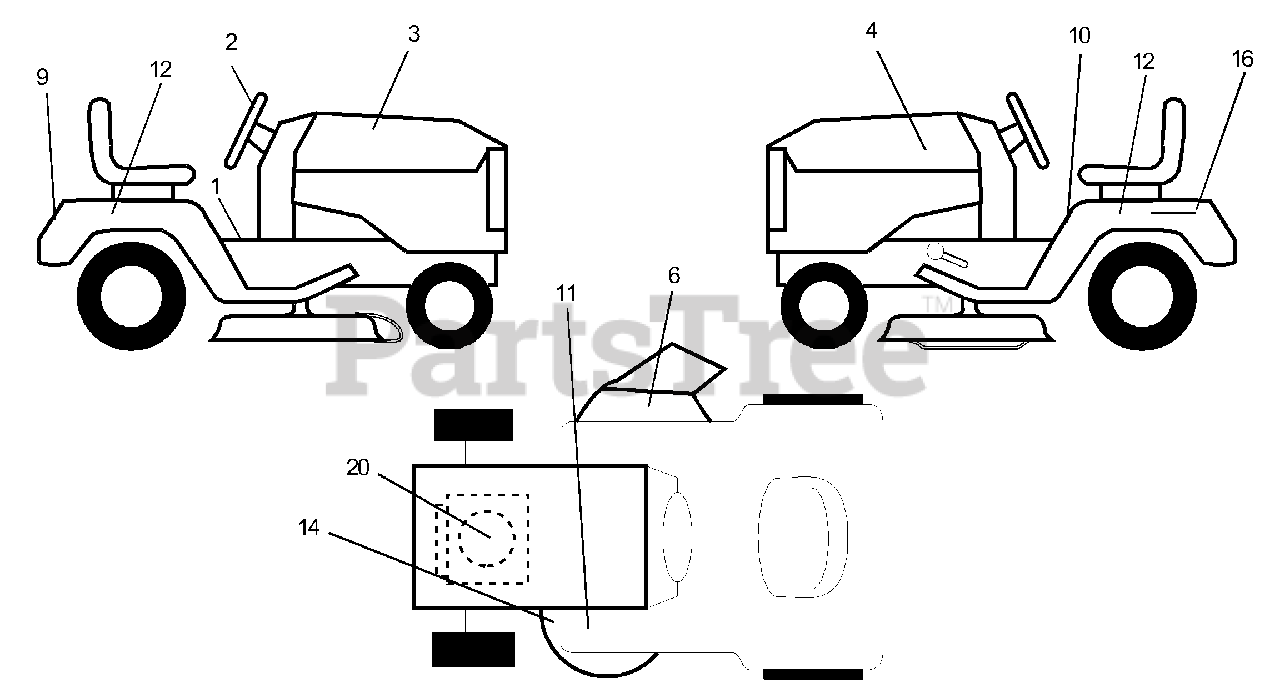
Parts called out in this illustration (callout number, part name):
1	Decal Instruction Operat English/French
2	Decal Ins Strg Wh
3	Decal Hood Rh
4	Decal Hood Lh
6	Decal, Warning
9	Decal Fender Logo
10	Decal Danger English
11	Decal Clutch/brake English
12	Decal Fender
14	Decal V-belt Schematic 42"
16	Decal Battery Danger/Poison
20	Decal HP Engine
